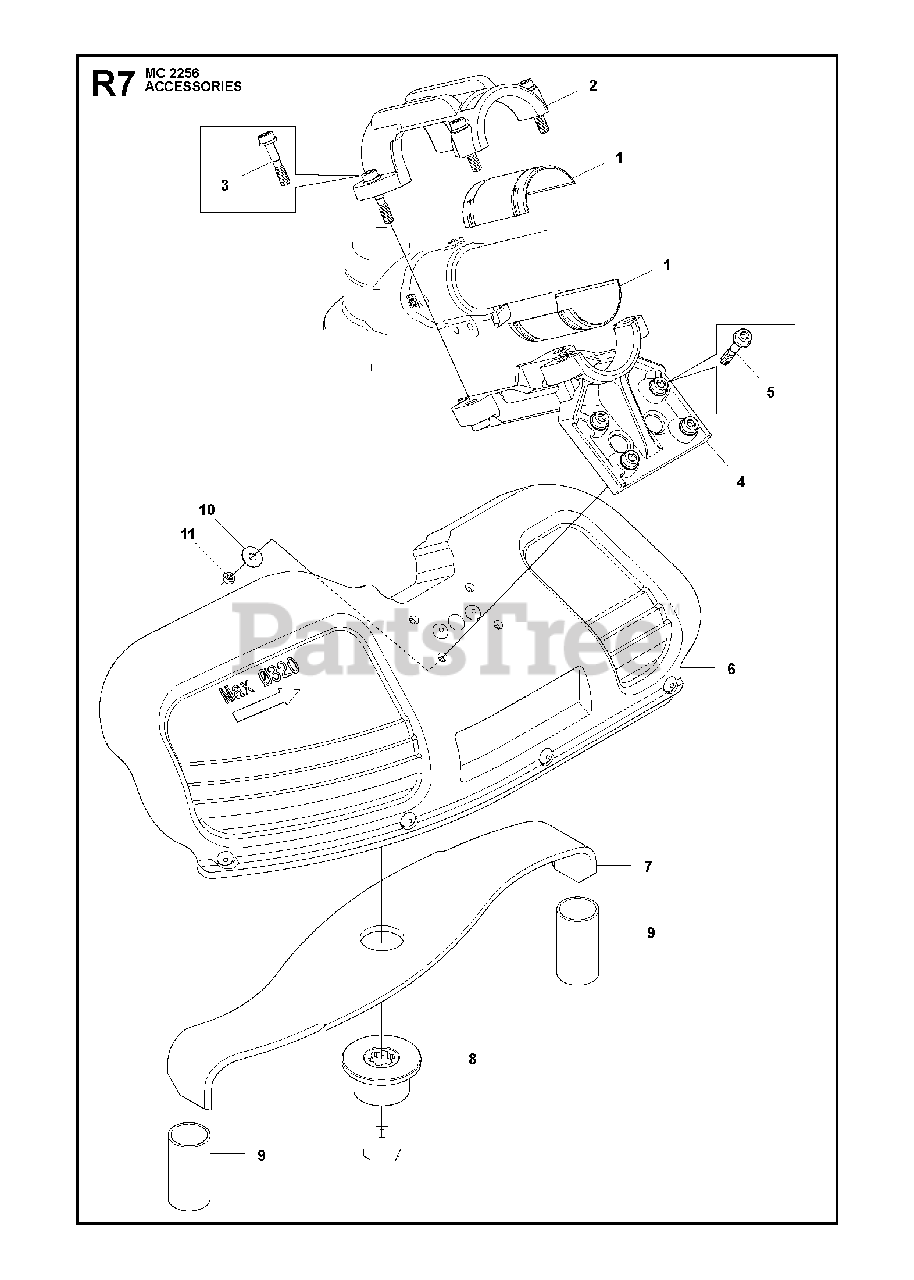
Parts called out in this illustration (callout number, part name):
3	SCREW IHSCFMO
5	SCREW IHSCFMO
7	BLADE NOT AVAIL IN US
8	SUPPORT FLANGE
9	TRANSPORT GUARD
11	LOCKNUT M5
